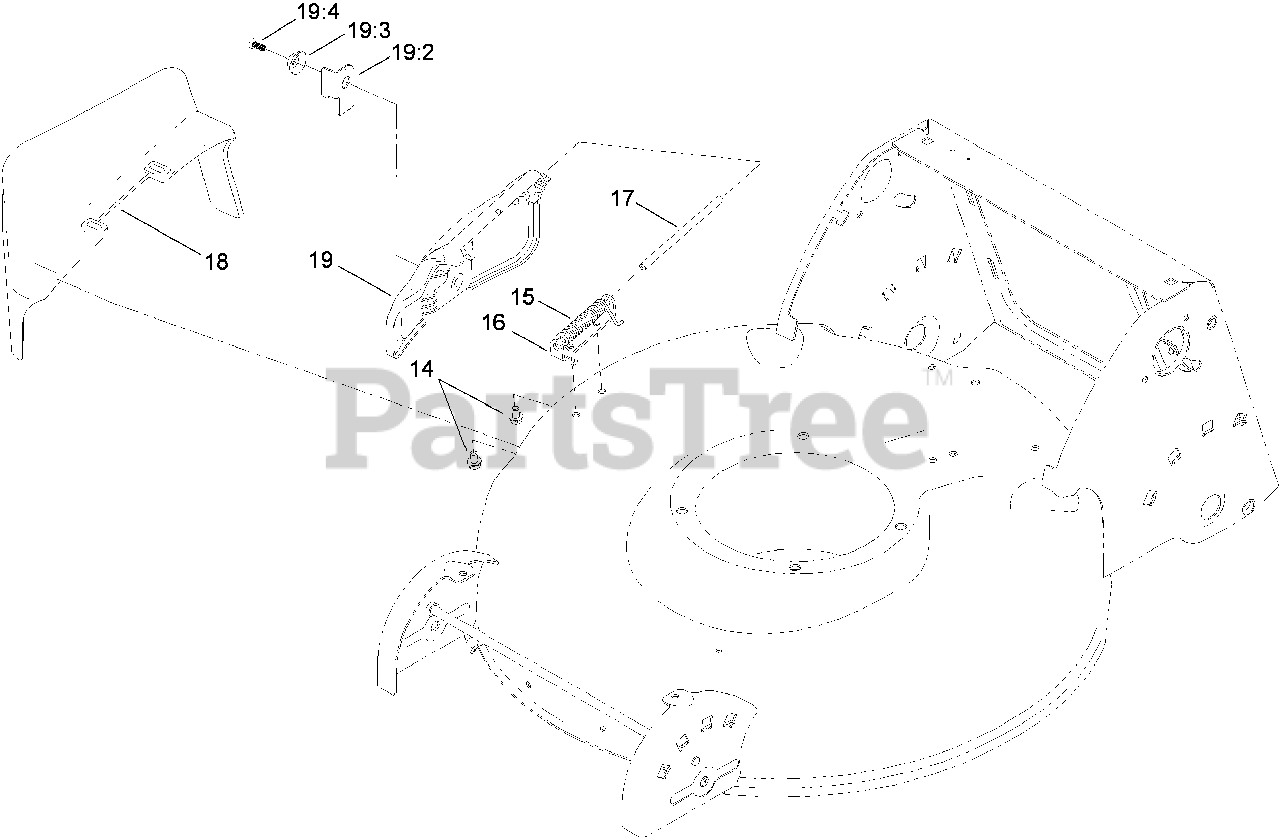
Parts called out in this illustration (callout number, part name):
14	SCREW-HWH
15	SPRING-TORSION
16	BRACKET-COVER
17	ROD-COVER
18	CHUTE-DISCHARGE, SIDE
19	DISCHARGE DOOR ASM
19:2	LATCH-DOOR
19:3	CAP-DOOR
19:4	SCREW-PLASTITE
